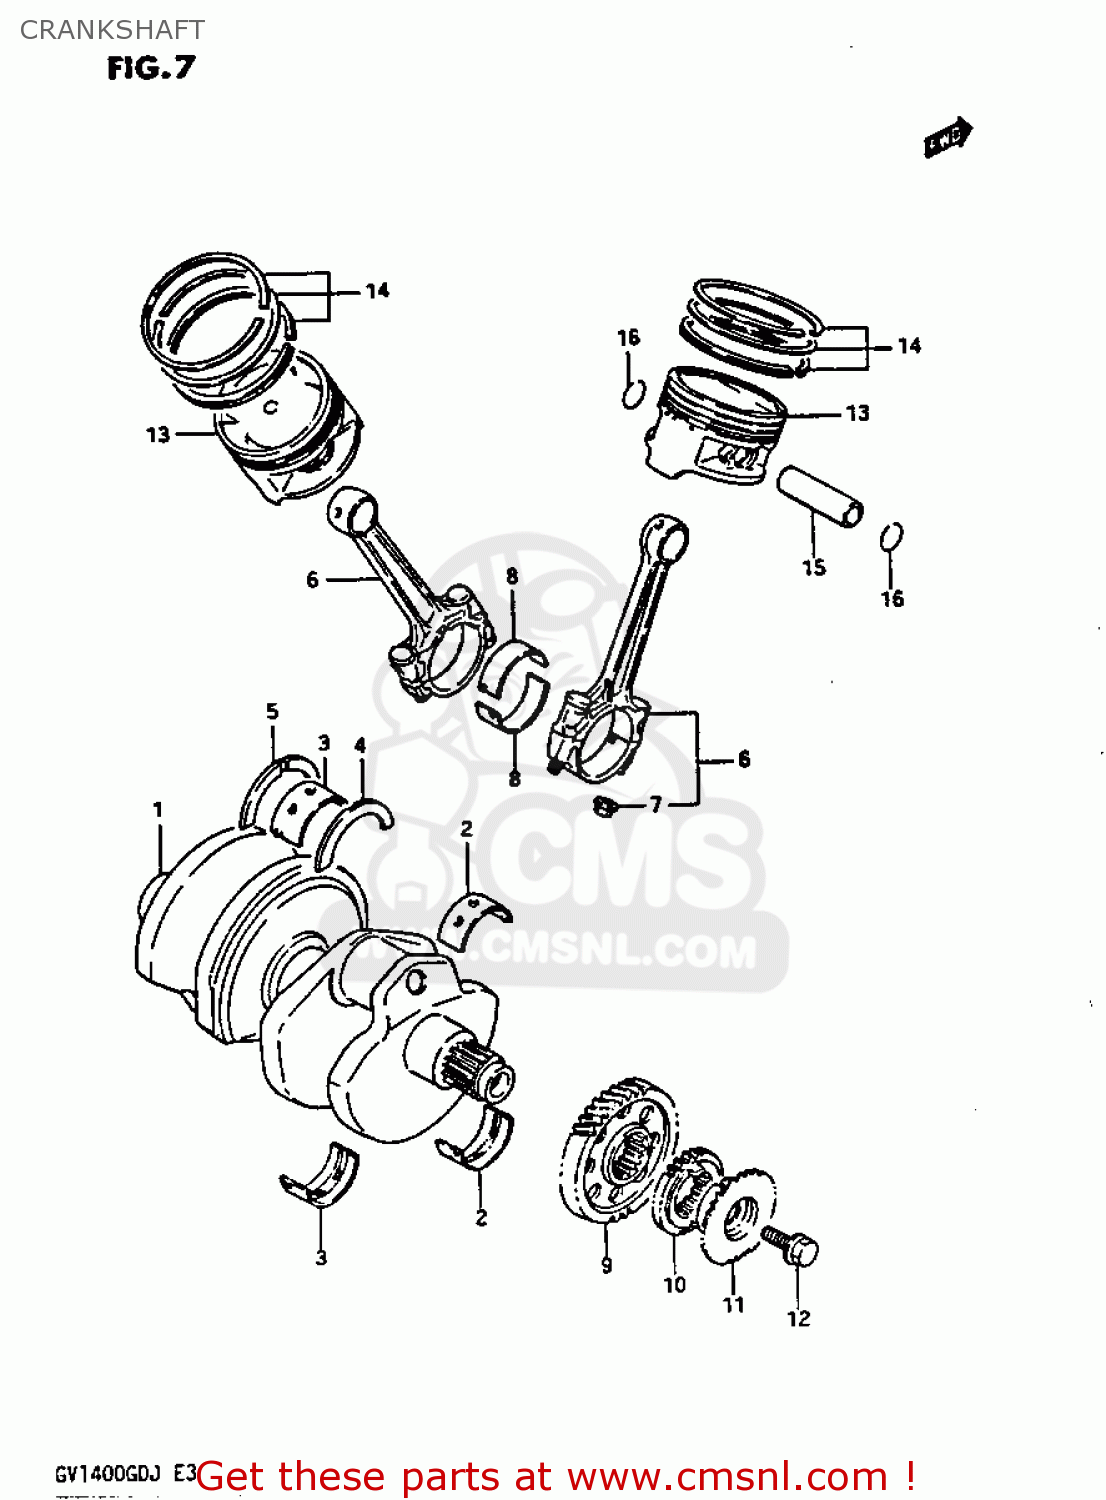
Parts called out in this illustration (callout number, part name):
1	CRANKSHAFT
2	METAL CRANKSHAFT
3	METAL CRANKSHAFT
4	PLATE,CRANK THRUST
5	PLATE,CRANK THRUST
6	CONNECTING ROD ASSEMBLY
7	NUT
8	BEARING,CRANK PIN
9	GEAR,PRIMARY DRIVE
10	SPROCKET,CHAIN DRIVE I
11	SPROCKET,WATER PUMP DRIVE
12	BOLT(10X24)
13	PISTON
14	RING SET,PISTON
15	PIN,PISTON
16	CIRCLIP,PISTON PIN
